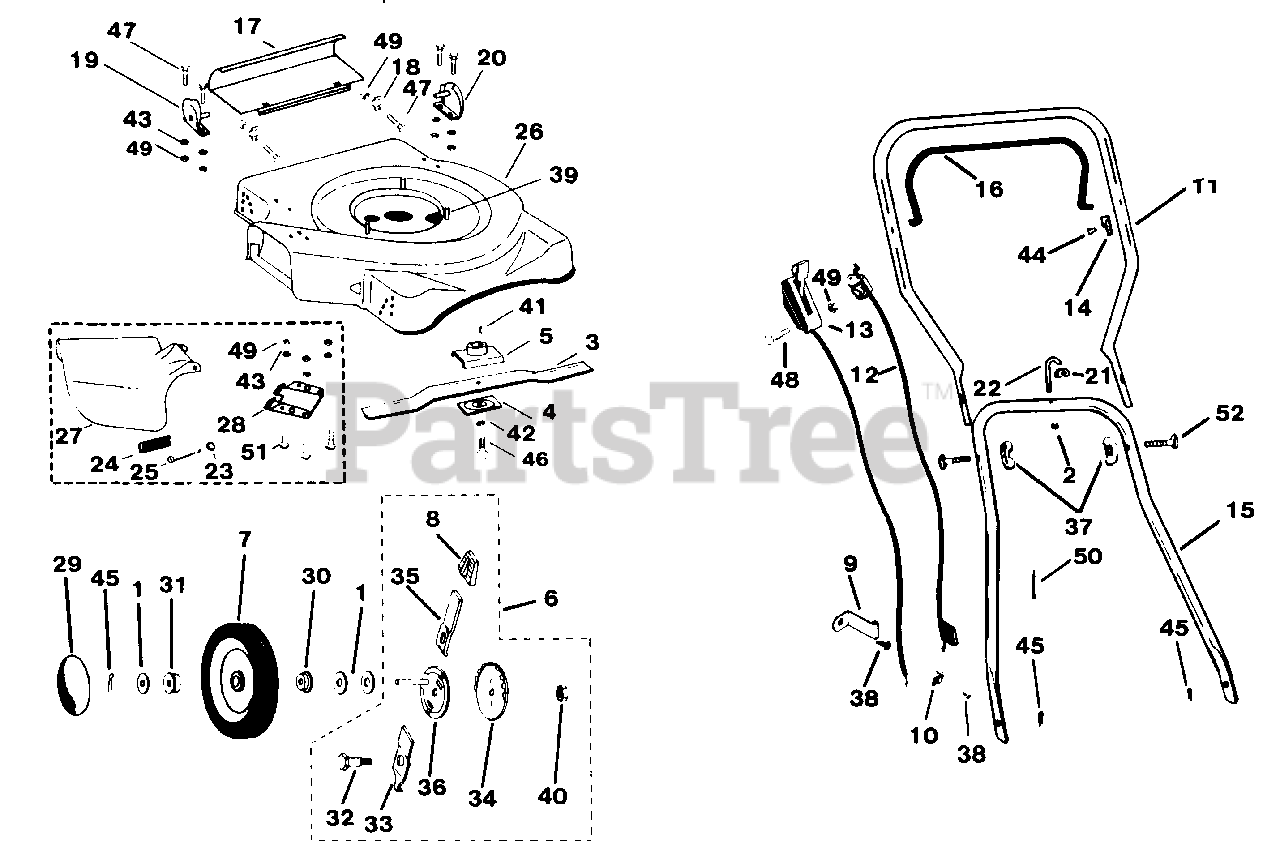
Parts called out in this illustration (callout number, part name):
2	Nut- .250-20 Keps
3	Blade-22"
4	Retainer Plate
5	Blade Adaptor
6	Height Adj. Ass'y.
7	Wheel Ass'y.-8"
9	Guide-Throttle Cable
10	Clamp-Throttle Control
11	Handle-Upper
12	Zone Restart Cable
13	Throttle Control
14	Brkt.-Bail Stop
15	Handle-Lower
17	Drag Guard-22"
18	Brkt.-Drag Pin Hinge
19	Brkt.-Handle-R.H.
20	Brkt.-Handle-L.H.
21	Rope Guide
24	Spring-Torsion
28	Hinge Bracket
30	Bearing-Inner
31	Bearing-Outer
32	Shoulder Bolt- .375-16 x 1.00
36	Plates Pin
38	Screw-#10 x .625
39	Screw- .375-16 x 1.00 Ind. Hex HD.
40	Nut-.375-16 Keps
41	Key, Woodruff .156 x .625
42	Lockwasher- .375
43	Washer .250
44	Screw-#10-32 x .50
45	Pin, Cotter .125 x .750
46	Capscrew, Hex Hd.-.375-24 x 1.250
47	Capscrew, Hex Hd.-.250-20 x .50
48	Capscrew, Hex Hd.-.250-20 x 2.00
49	Nut, Lock .250-20
50	Plastic Cable Tie
51	Bolt, Carriage .250-20 x .50
52	Saddle Bolt- .312 18 x 1.750
52	Decal-Danger (Side deck in Front of discharge opening)
52	Decal-Simplicity (Top of Deck)
52	Decal-22" (On front lip of Deck)
52	Decal-Be Careful (Rear top of Deck)
52	Decal-Caution (On Guard)
52	Decal-Caution (By Deflector)
52	Decal-Start & Stop (On top of upper handle)
